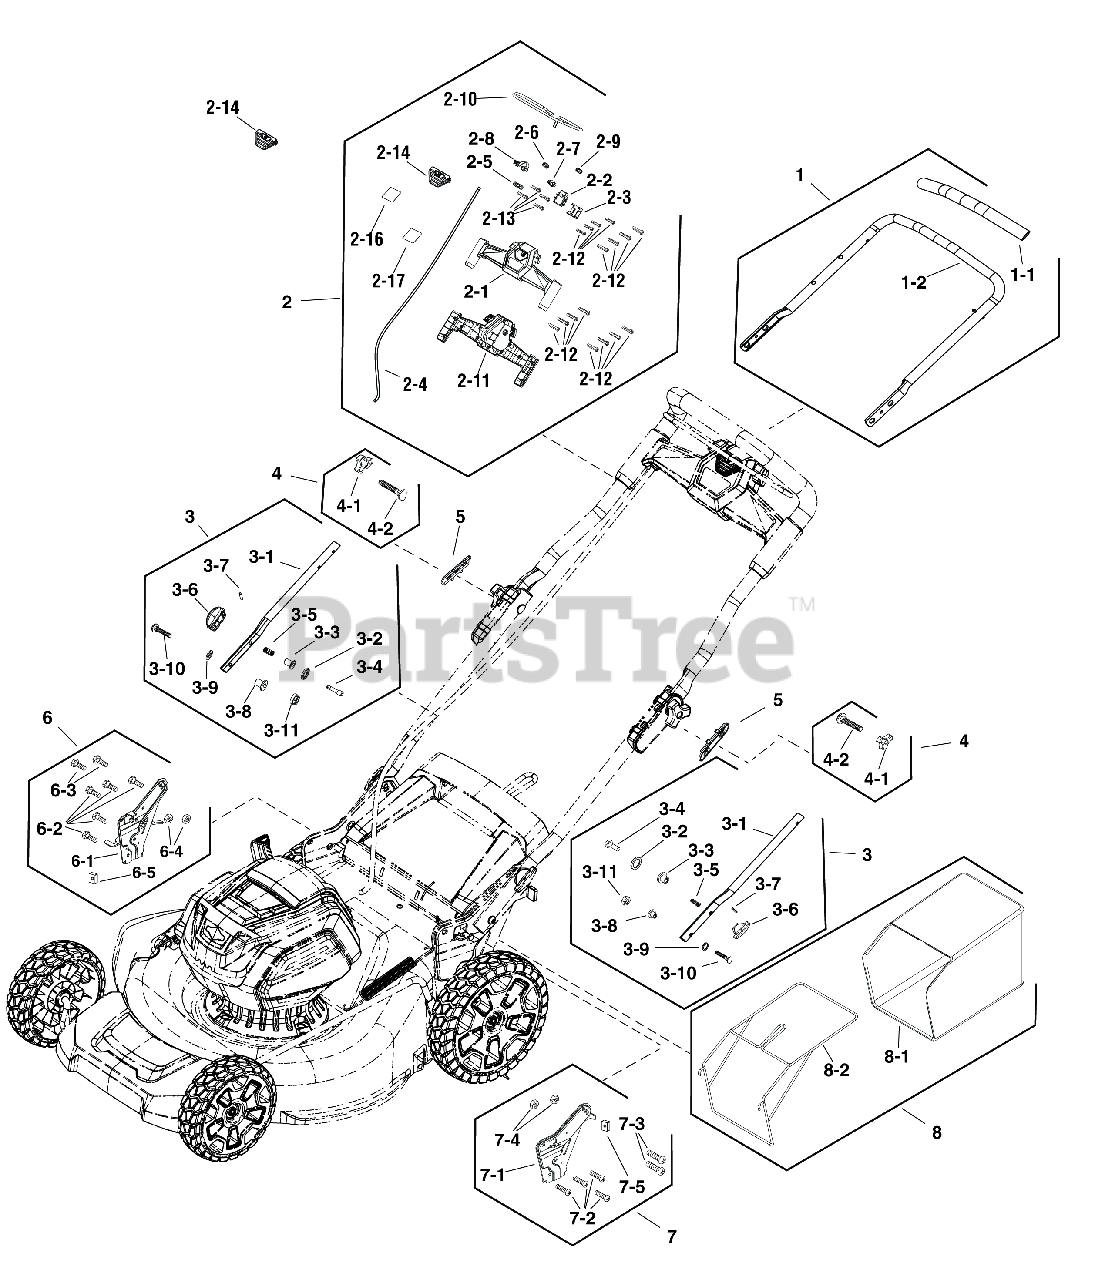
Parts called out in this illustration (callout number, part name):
1	KIT, UPPER HANDLE
1-1	SPONGE
1-2	UPPER HANDLE
2	KIT, SWITCH BOX
2-1	PANEL, Dash
2-3	INSERT
2-4	CABLE
2-5	CLAMP
2-6	SPRING
2-7	DISC, Tension
2-8	CLAMP, Cable
2-9	SPRING
2-10	BAR
2-11	PANEL, Dash
2-13	SCREW
2-14	BUTTON, Start
2-16	LABEL
2-17	DECAL
3	KIT, Lower Handle
3-1	LOWER HANDLE
3-2	GASKET
3-3	INSERT
3-4	POST
3-5	SPRING
3-6	KNOB
3-7	PIN
3-8	BLOCK
3-9	WASHER, Flat
3-10	BOLT
3-11	NUT
4	KIT, HARDWARE
4-2	BOLT
5	KIT, HARDWARE
6	KIT, RIGHT BRACKET
6-1	ADJUSTMENT BRACKET
6-2	SCREW
6-3	BOLT
6-4	NUT
6-5	BUMPER
7	KIT, LEFT BRACKET
7-1	BRACKET, Height Adjust
7-2	SCREW
7-3	BOLT
7-4	NUT
8	KIT, GRASS BAGGER
8-1	FRAME
8-2	BAG, Grass Catcher
